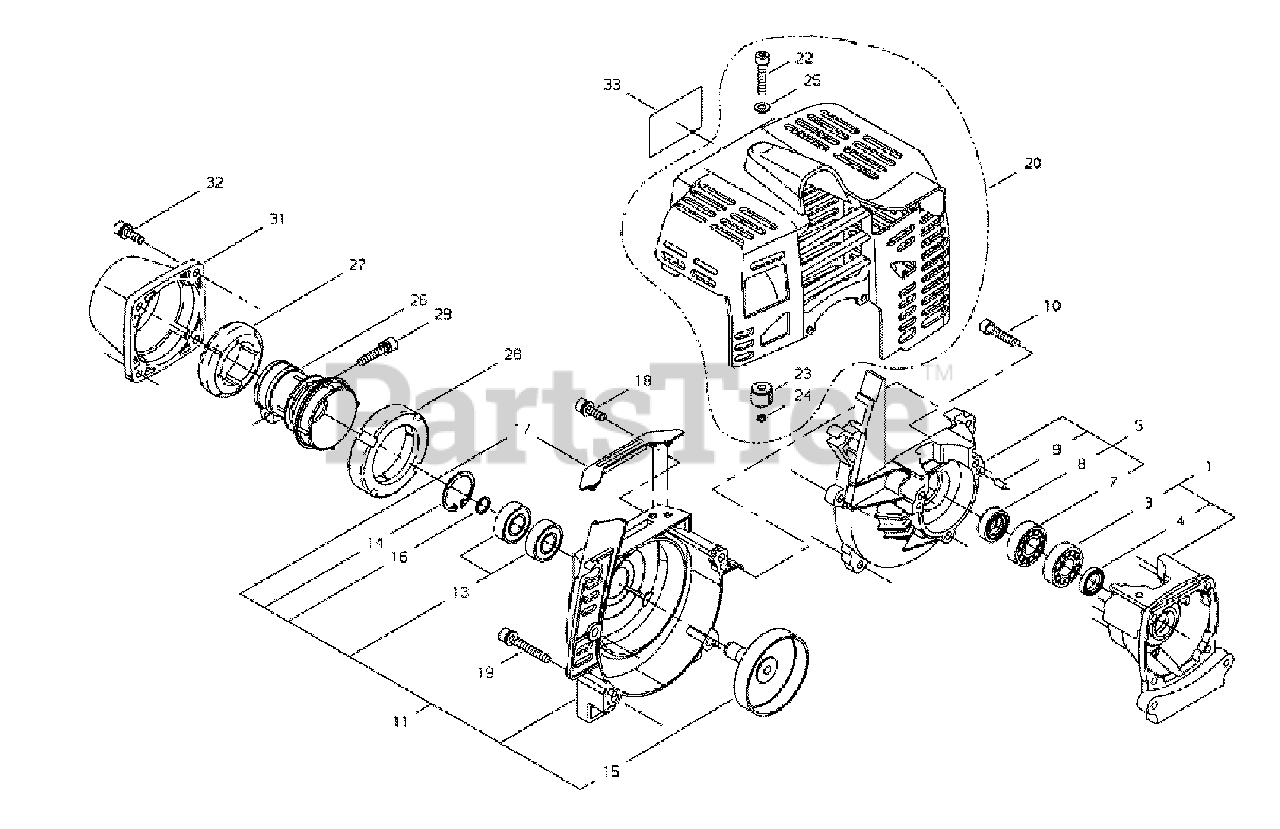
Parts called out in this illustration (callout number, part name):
1	CRANKCASE ASSY - REAR
3	BEARING, BALL - 6001C3
4	SEAL, OIL
5	CRANKCASE ASSY - FRONT
7	BEARING, BALL - 6001C3
8	SEAL, OIL - 12
9	PIN - LOCATING
10	SCREW - 5X25
11	FAN CASE ASSY
13	BEARING, BALL - 6000
14	RING, RETAINING - 26
15	DRUM, CLUTCH
16	RING, RETAINING
17	CUSHION
18	SCREW - 5X16
19	SCREW - 5X45
20	ENGINE COVER KIT
22	SCREW - 5X25
23	INSULATOR
24	CLIP
25	WASHER - 5
26	CLAMP, MAIN PIPE
27	CUSHION - FRONT
28	CUSHION - REAR
29	SCREW - 5X25
31	CAP
32	SCREW - 5X16
33	LABEL - MODEL AHS231
